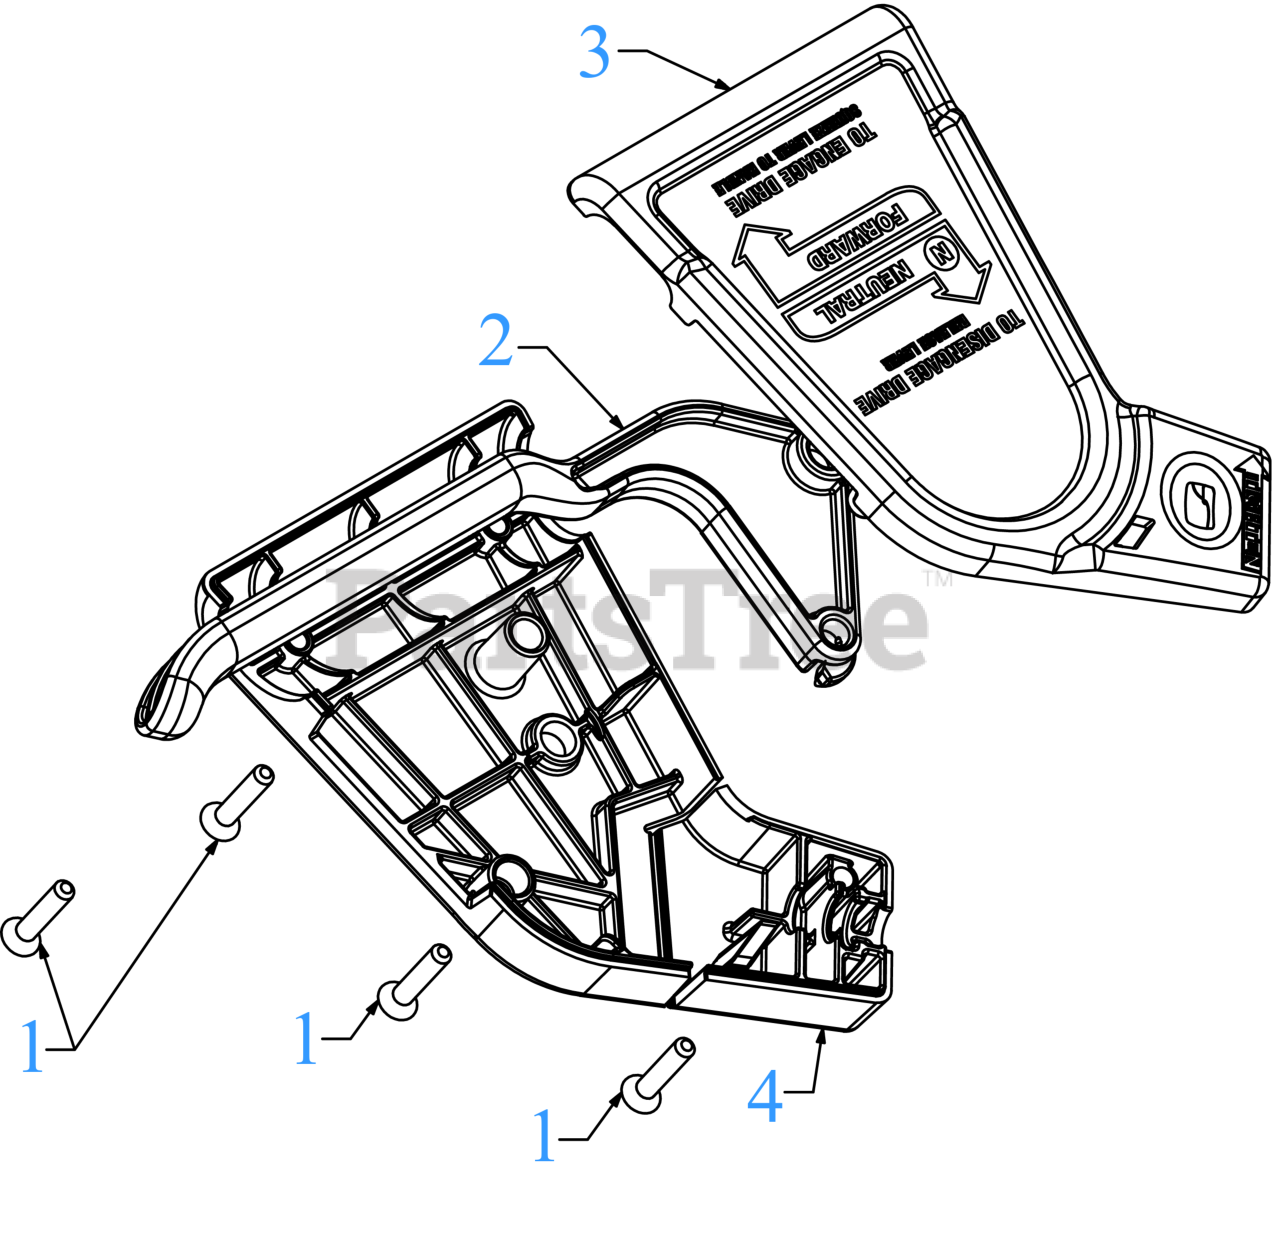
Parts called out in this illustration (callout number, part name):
1	SCREW #10-16 x 1.00
2	ENGAGEMENT LEVER
3	KIT-DRIVE CONTROL
4	SQUEEZEBOX CONTROL COVER
